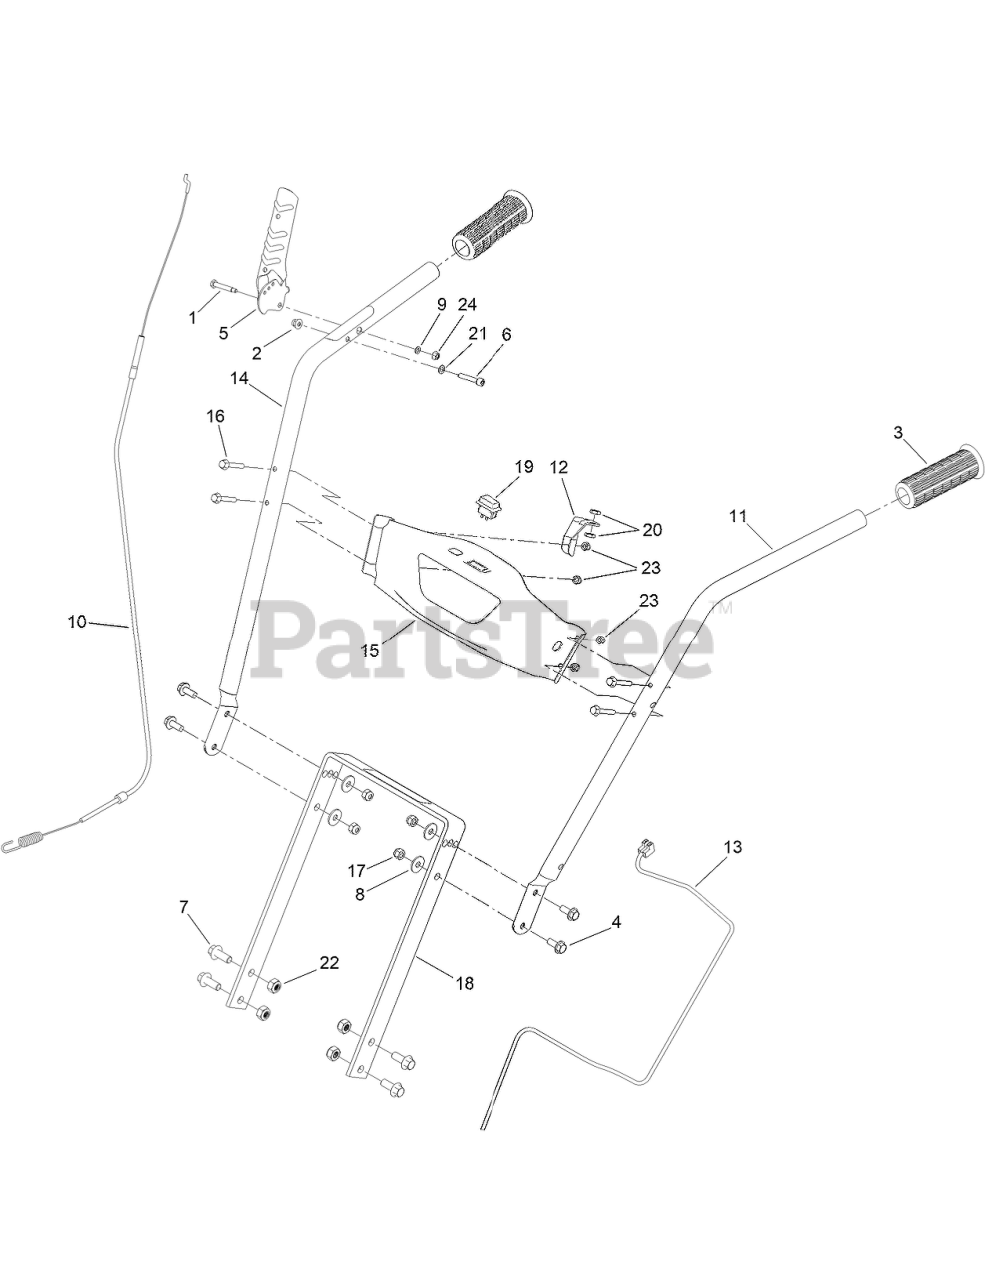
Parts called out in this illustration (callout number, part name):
1	SCREW-HH
2	NUT-HEX
4	SCREW-HSF
5	LEVER-CLUTCH
6	SCREW-SHCS
7	SCREW-RHSF
8	WASHER-FLAT
9	NUT-HEX
10	WASHER-FLAT
11	DRIVE-CABLE
12	HANDLEBAR-LEFT
13	BRACKET-CABLE
14	HARNESS-WIRING
15	HANDLEBAR-RIGHT
16	DASH-TILLER
17	SCREW-HHF
18	NUT-HEX
19	MOUNT-HANDLEBAR
20	SWITCH
22	WASHER
23	NUT-HEX
24	NUT-HEX
